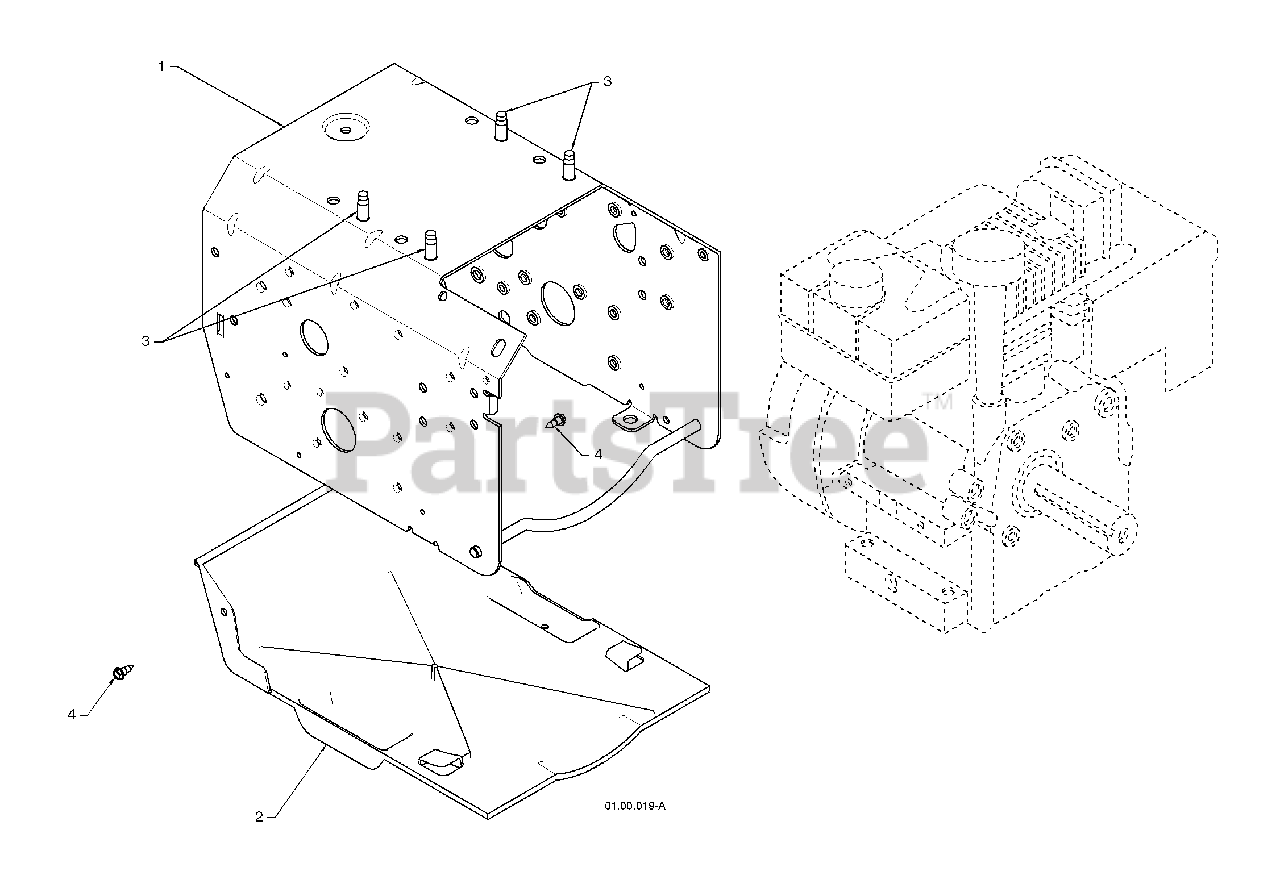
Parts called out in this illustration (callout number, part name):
2	BOTTOM PAN
3	BOLT 3/8-16
4	SCREW 10-24 X .625
